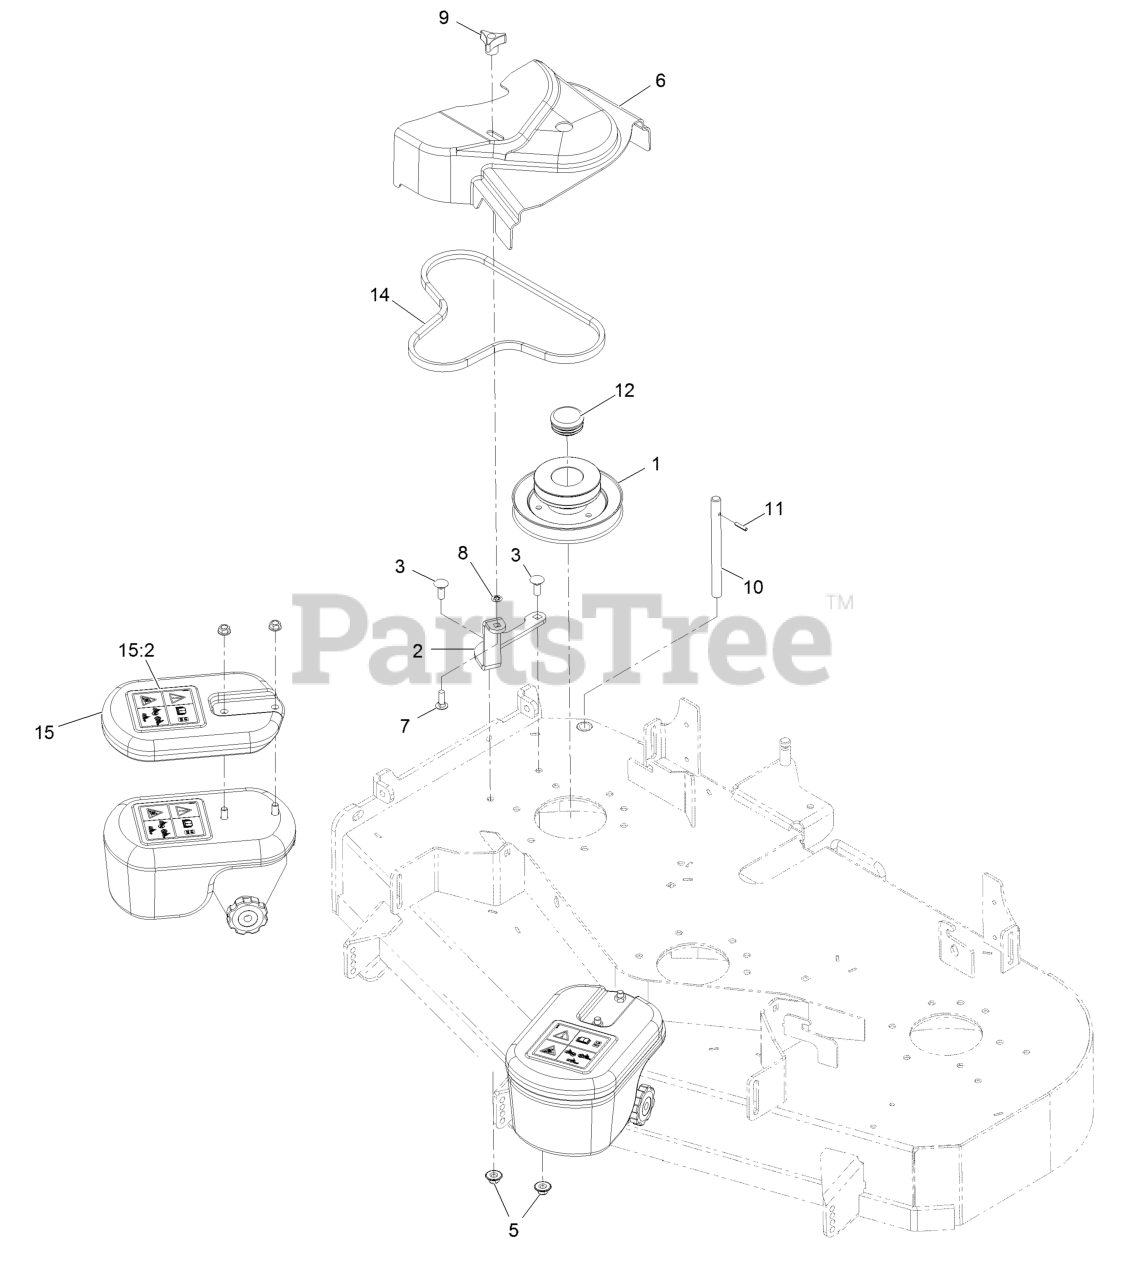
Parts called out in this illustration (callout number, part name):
1	Jackshaft-Uv Drive, 484 Splined
2	Bracket, Small Uv Belt Cover
3	Bolt-CARR
5	Nut-Flange, NI
6	Cover-Belt, Uv 48
7	Bolt-CARR
8	Ring-Retaining, Bolt
9	Knob-3 Prong
10	Shaft-Catcher, Grass
11	Pin-Roll
12	Plug-Round Plastic
14	Belt, Blower (48")
15:2	Decal-Warning, Traction
